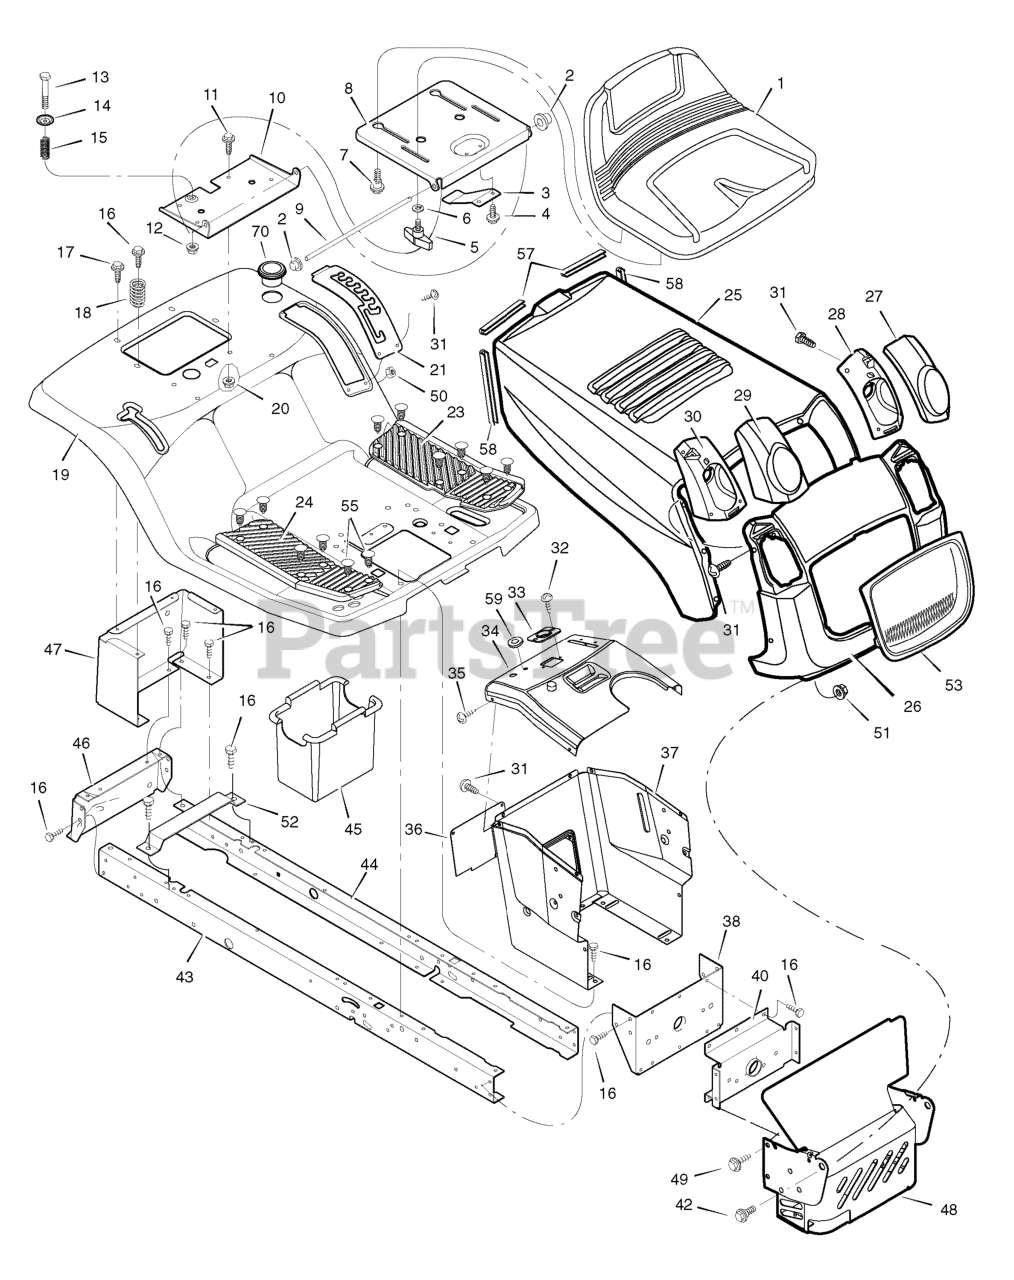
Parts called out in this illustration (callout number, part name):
1	Seat
2	Cap, Push 0n
5	Bolt, Wing
6	Washer
7	Bolt, Shoulder
8	Support, Seat
9	Rod, Pivot
10	Bracket, Pivot
11	Bolt
13	Bolt, Shoulder
20	Nut
21	Plate, Index Detent
23	Mat, Left
24	Mat, Right
26	Grille
27	Lens, Left
28	Housing, Left Headlamp
29	Lens, Right
30	Housing, Right Headlamp
33	Bearing, Steering
34	Dash
36	Panel, Access
37	Support, Dash
38	Bracket, Rear Hanger
40	Axle, Hanger
42	Bolt
43	Frame, Right
44	Frame, Left
45	Container, Battery
46	Plate, Hitch
47	Panel, Rear
48	SHIELD, Heat
51	Nut
52	Support, Battery
53	Insert, Grille
55	Fastener, Panel
57	Trim, Hood (3.75")
58	Trim, Hood (6.5")
59	Grommet, Parking Brake
70	Holder, Cup
